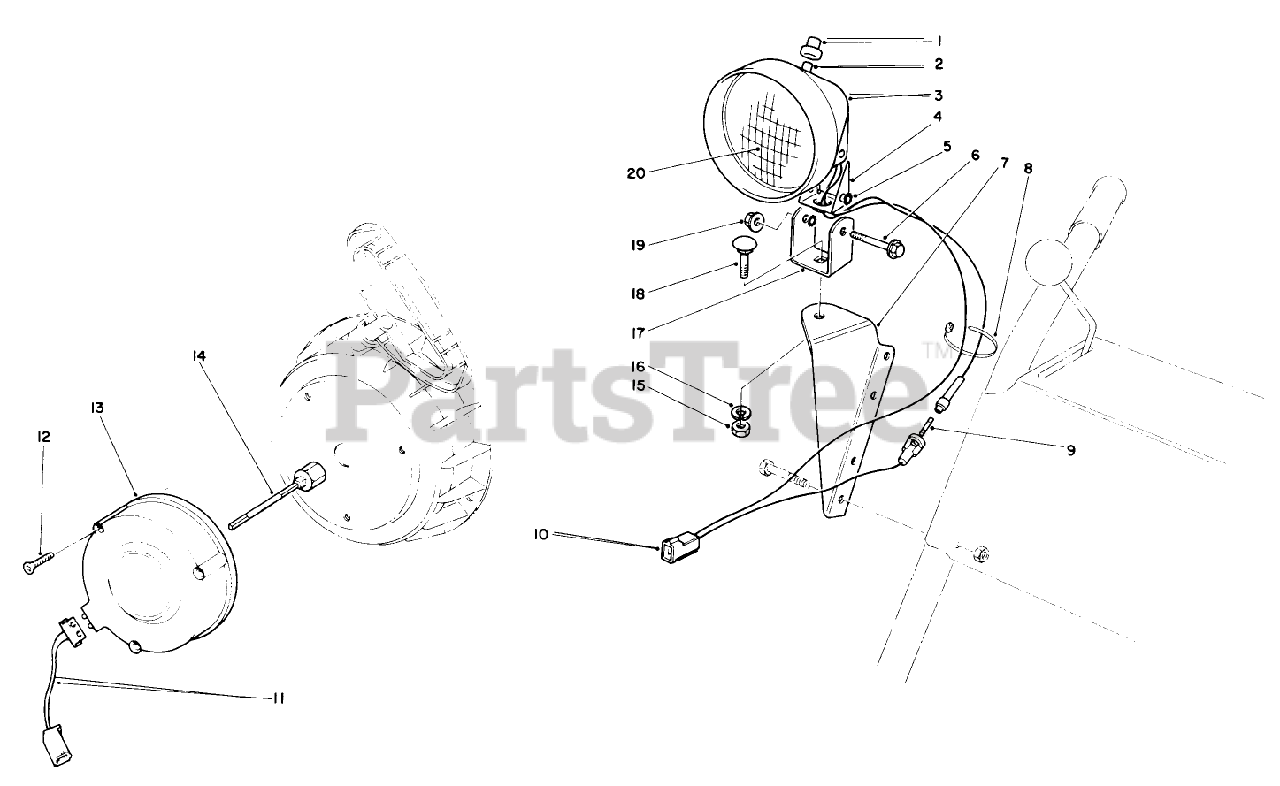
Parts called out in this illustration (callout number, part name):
1	BOOT-SWITCH
5	WASHER-LOCK
6	SCREW-HH
7	MOUNT-LAMP
8	TIE-CABLE
9	Fuse-7 1/2 Amp.
10	WIRE ASM
13	TECUMSEH 1A183-69
14	TECUMSEH 1A52-194
15	NUT-HEX
16	WASHER-LOCK
18	BOLT-CARR
19	NUT-HF
20	BEAM-SEALED
